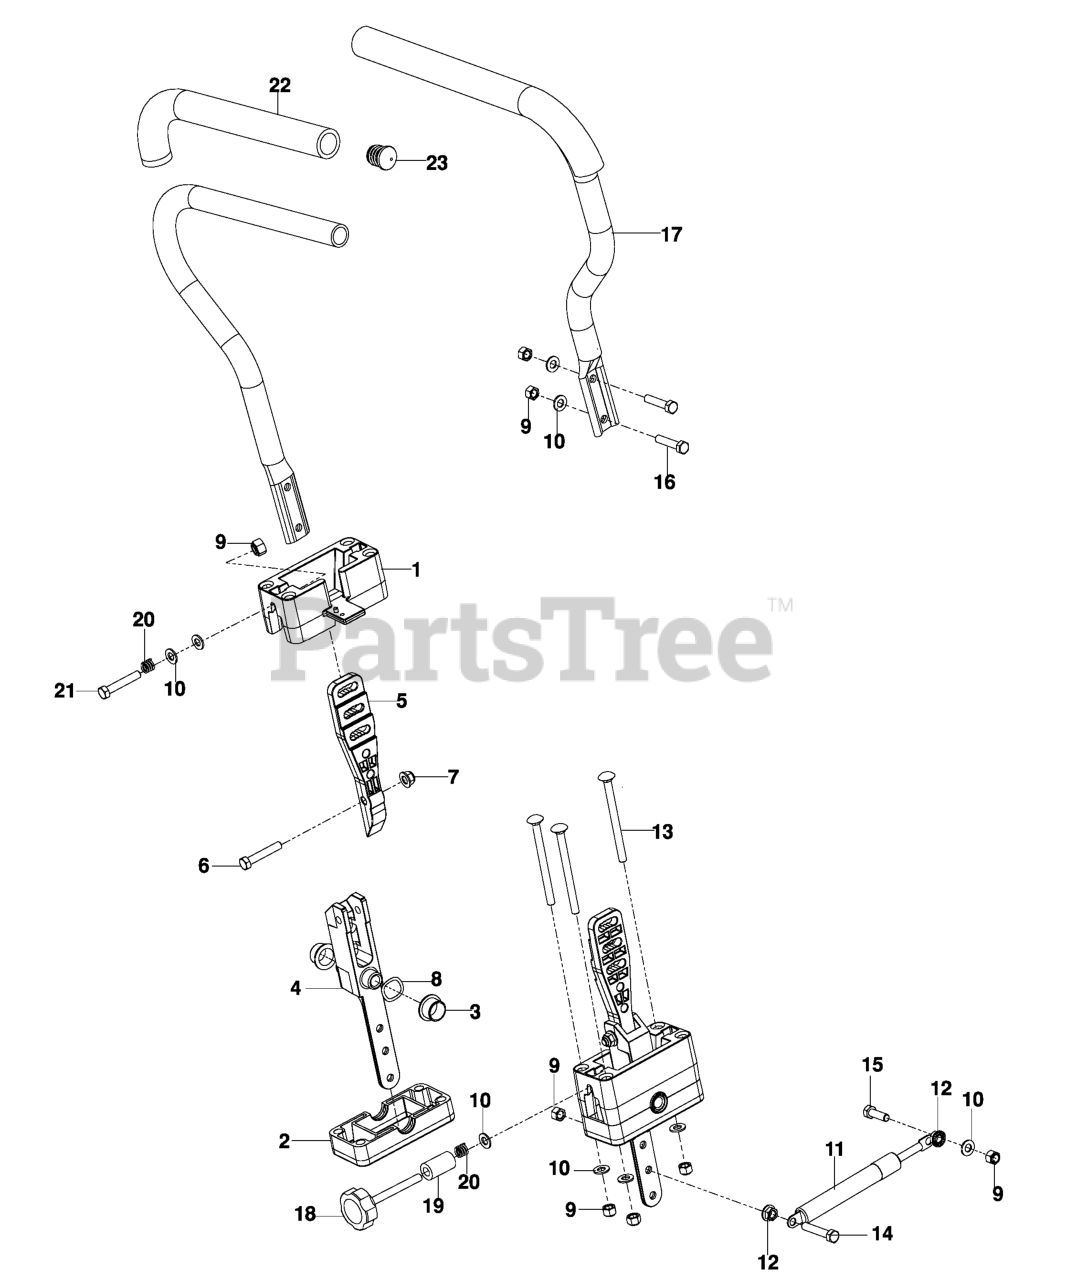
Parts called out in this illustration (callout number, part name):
1	BLOCK, UPPER
2	BLOCK, LOWER
3	BEARING, FLANGE
4	PIVOT.SECTION.DRIVE.CONTROL
5	MOUNT, DR CNTRL HANDLE
6	HCS 5/16C X 1 3/4
7	5/16-18 NYLOC FLANGE NUT
8	WASHER, .825 X 1.087, WAVE
9	NUT 5/16 NYLOC
10	FLAT WASHER 5/16 SAE
12	NUT 5/16C WHIZ
13	RHSNB 5/16-18 X 4 GR 5 ZD
14	HCS 5/16-18X1-3/4 TPBLT
15	HCS 5/16C X 1
16	CAPSCREW 5/16 X 1/1/2 HEX HEAD
17	LEVER.DRIVE.W/GRIP
21	HCS 5/16-18 X 2 TPBLT GR 5 ZD
22	GRIP, FOAM (GROUND) 15
23	END PLUG 15/16 (BLACK)
